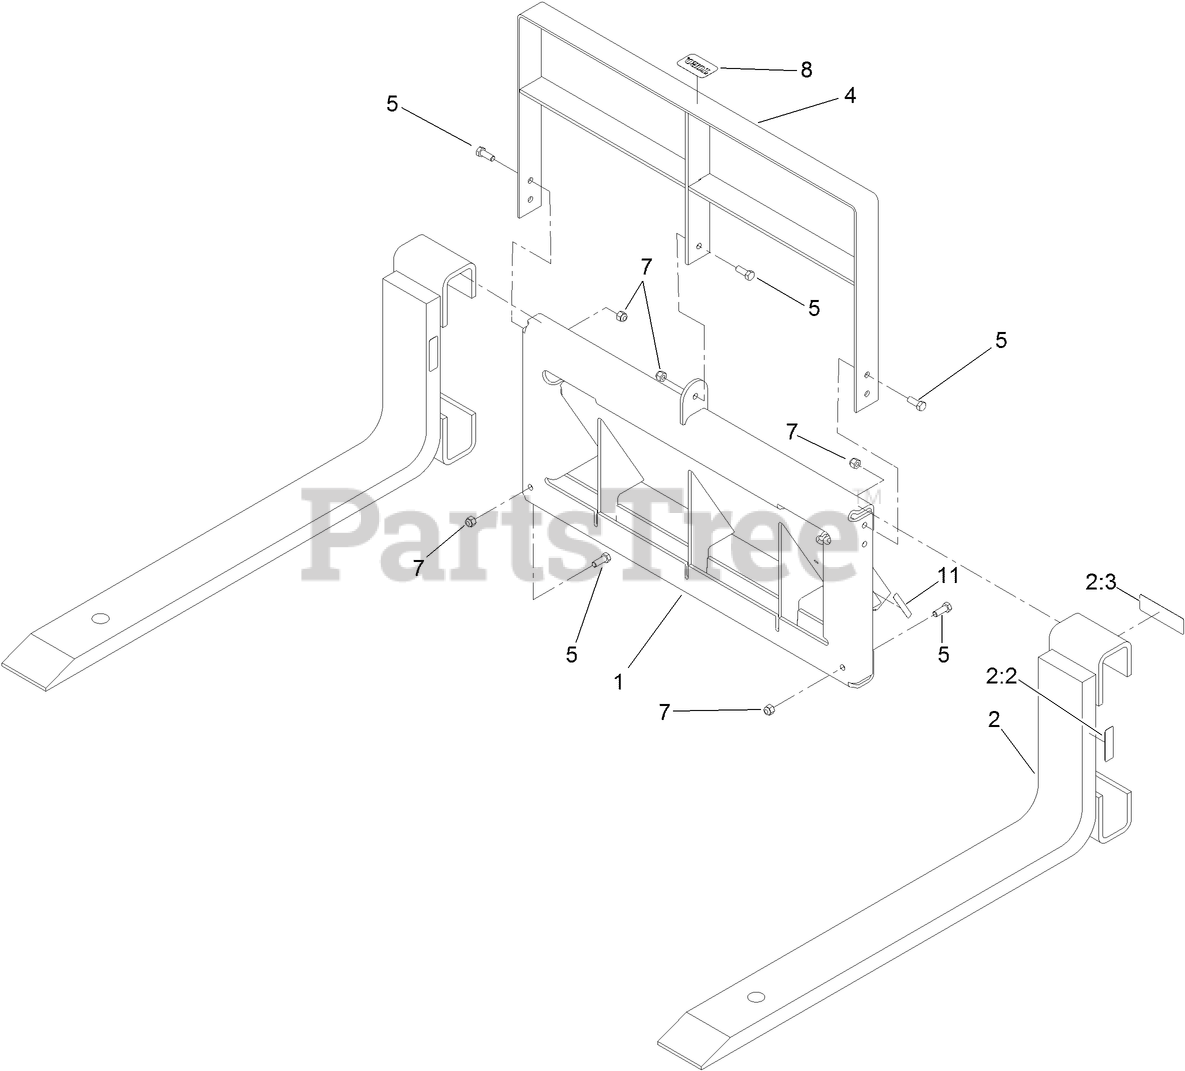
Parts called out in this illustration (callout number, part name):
1	FRAME-FORK
2	FORK ASM
2:2	DECAL-CAPACITY
2:3	DECAL-CAPACITY
4	FRAME-FORK, UPPER
5	SCREW-HH
7	NUT-LOCK, NI
8	DECAL
11	DECAL-WARNING
